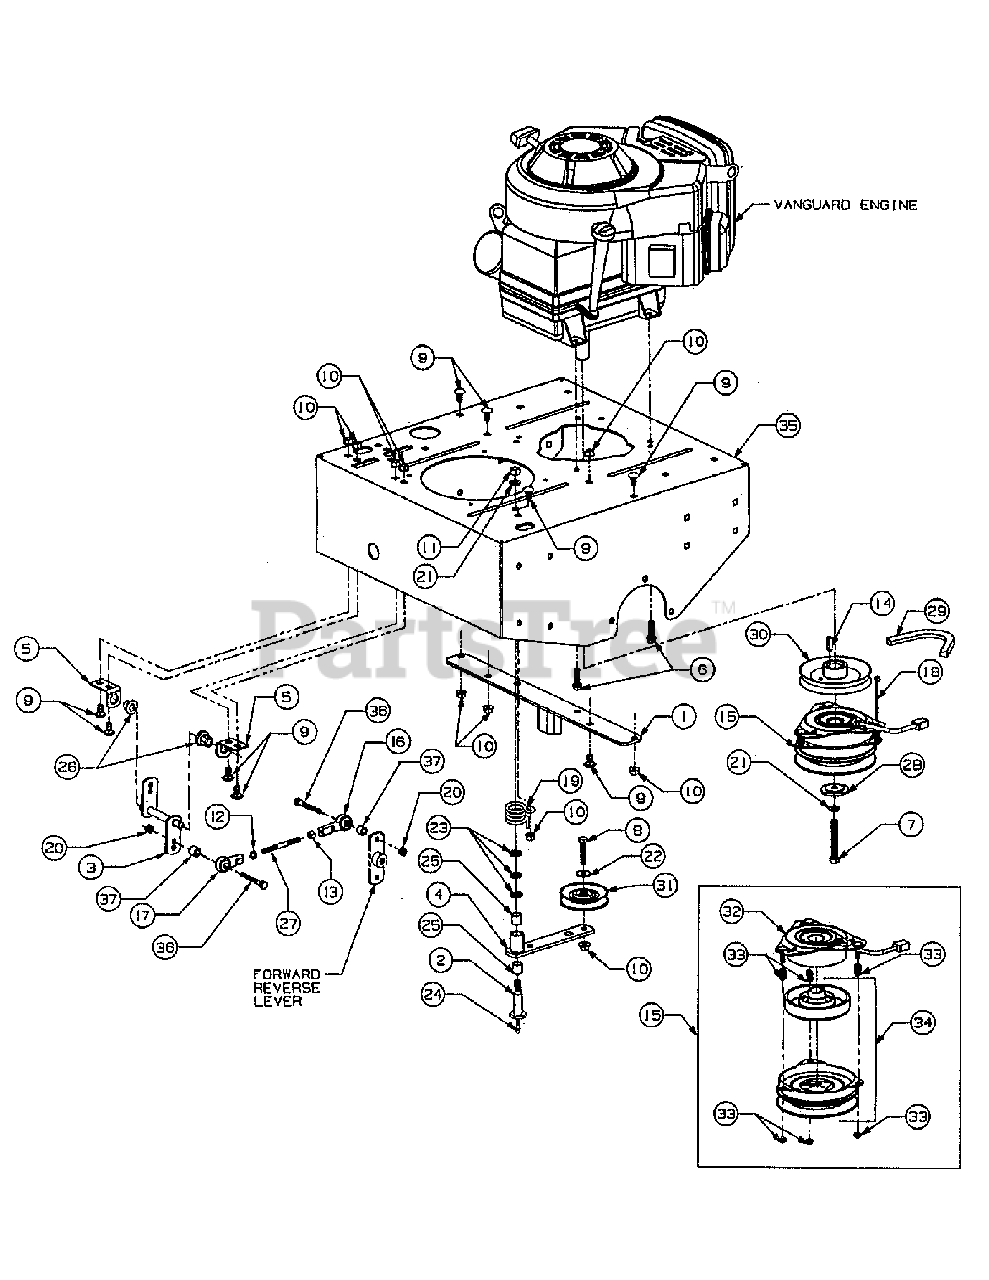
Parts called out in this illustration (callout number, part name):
3	Lever, F/R Control
4	Arm Assembly, Idler
5	Bracket, Lever Angle
6	Screw, Hex L-Wash Tapp, 3/8-16 x 1.25
7	Screw, Hex Cap, 7/16-20 x 3.0 Gr 5
8	Screw, Hex Cap, 3/8-16 x 1.75
9	Bolt, Sht Nk Carraige, 3/8-16 x .75 Gr 5
10	Nut, Hex Flanged Lock, 3/8-16
11	Nut, Hex, 7/16-14 Gr 5
12	Nut, Hex Jam, 5/16-24 LH Thread
13	Nut, Hex, 5/16-24 Gr 5
14	Key, Square, 1/4 x 1.0
15	Clutch Assembly
16	Rod End, Sperical 5/16-24
17	Rod End, Sperical 5/16-24 LH Thread
18	Cable Tie
19	Spring, Torsion
20	Nut, Hex Flange Lock, 5/16-18 Gr 5
21	Washer, Lock 7/16
22	Washer, Special .378 x 1.00 x .125 Thk
23	Washer, Flat .469 x .875 x .105 Thk
24	Fitting, Lube
25	Bearing, Sleeve
26	Bearing, Hex Flange
27	Rod, Control
28	Spacer, Clutch
29	Belt, Tranmission, 1/2 x 40.0
30	Pulley, Engine
31	Pulley, V-Idler
32	Field Assembly
33	Mounting Accessories
34	Kit, Armature & Rotor
35	Deck w/Graphics, Engine Mtg
35	Graphic, Warning
36	Screw, Hex Cap 5/16-18 x 1.38 Gr 5
37	Spacer, .317 ID x .625 OD x .343
